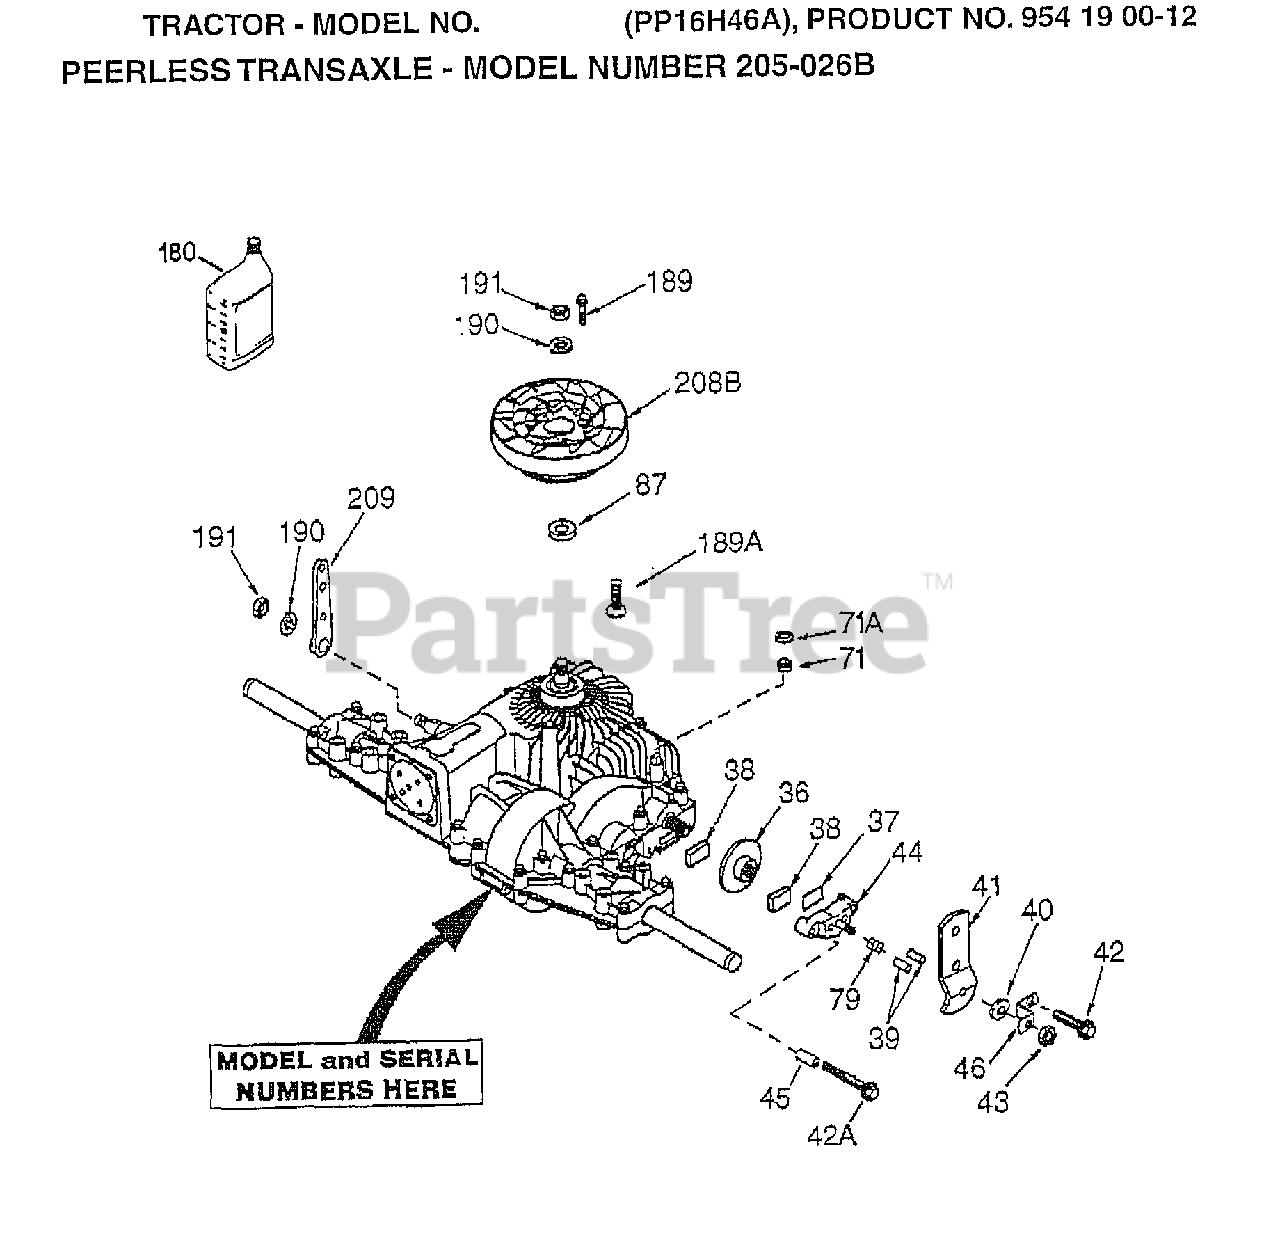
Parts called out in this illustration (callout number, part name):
37	PLATE BRAKE PAD
41	BRAKE LEVER
42	SCREW, 1/4-20 X 1-1/4
42A	SCREW, 1/4-20 X 2-1/4
43	LOCKNUT 5/16-24
44	HOLDER BRAKE PAD
46	BRAKE LEVER BRACKET
71	SEAL SQUARE CUT
180	GEAR OIL 80W90
189	DRIVE SCREW
208B	FAN/COUPLING
209	CONTROL LEVER
